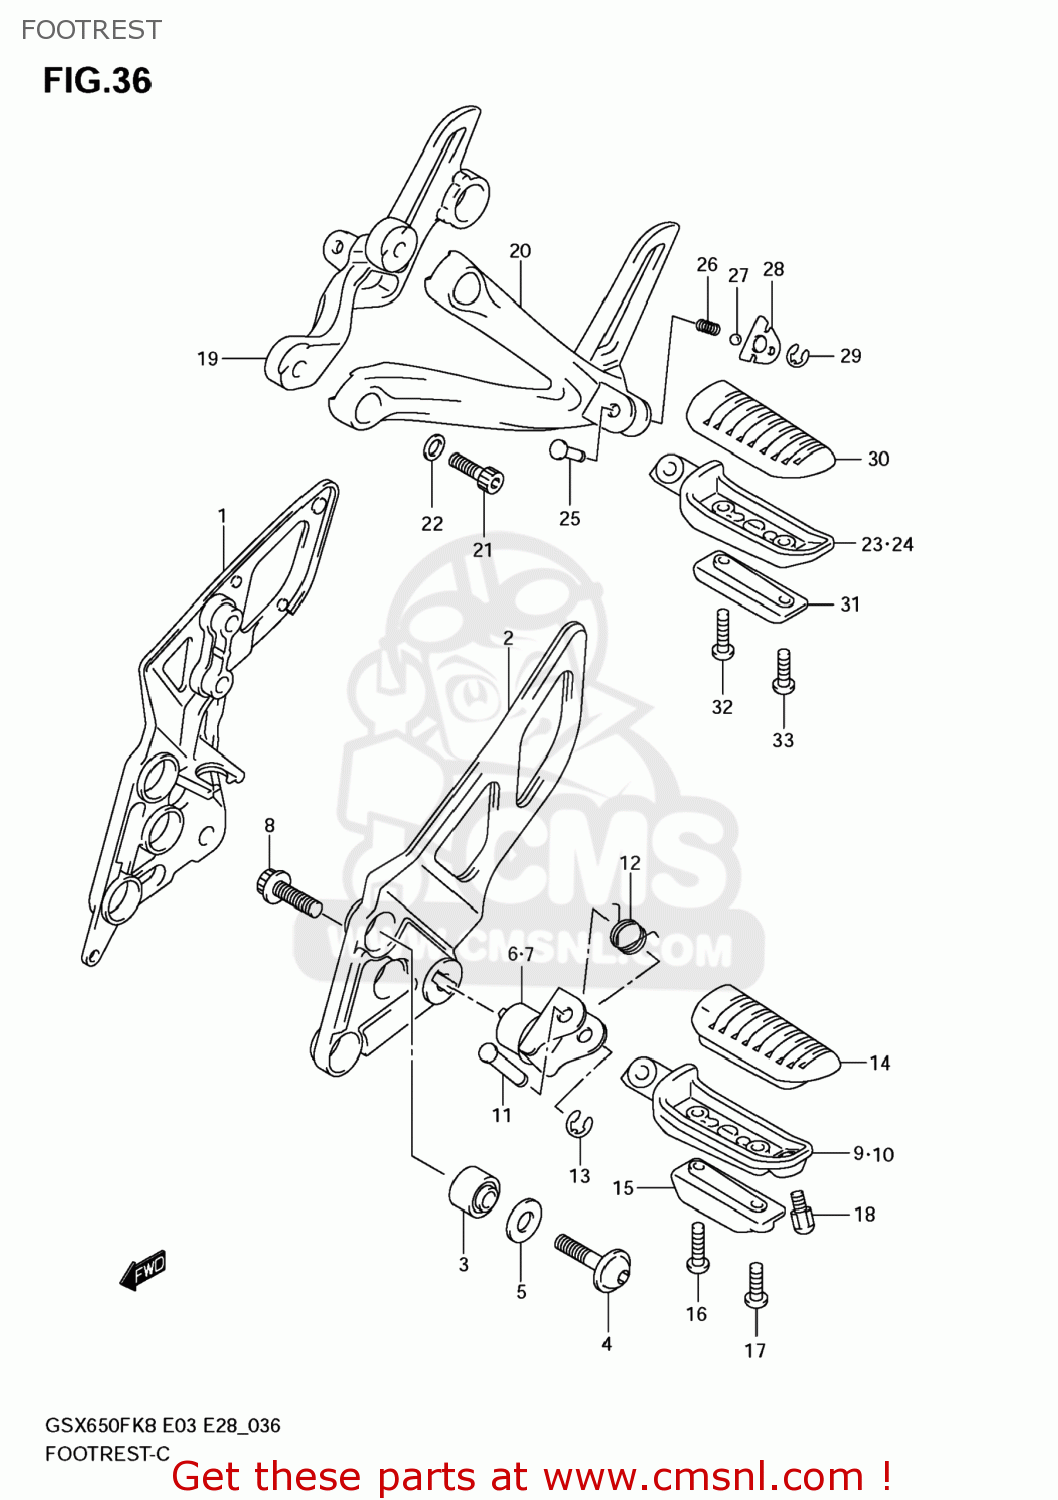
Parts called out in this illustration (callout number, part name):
1	BRACKET,FR FOOTREST,R
2	BRACKET,FR FOOTREST,L
3	BUSH(8.2X22.3X16.5)
4	BOLT(8X30)
5	WASHER(12.6X24X1.9)
6	HOLDER,FR FOOTREST,R
7	HOLDER,FR FOOTREST,L
8	BOLT(10X28)
9	BAR,FR FOOTREST,R
10	BAR,FR FOOTREST,L
11	PIN
12	SPRING
13	E RING
14	RUBBER,FOOTREST
15	BALANCER,FR FOOTREST
16	SCREW
17	SCREW
18	BOLT,BANK SENSOR
19	BRACKET,PILLION FOOTREST,R
20	BRACKET,PILLION FOOTREST,L
21	BOLT(8X25)
22	WASHER
23	BAR,PILLION FOOTREST,R
24	BAR,PILLION FOOTREST,L
25	PIN
26	SPRING
27	BALL
28	PLATE,PILLION
29	E RING
30	RUBBER,FOOTREST
31	BALANCER,PILLION FOOTREST
32	SCREW
33	SCREW
